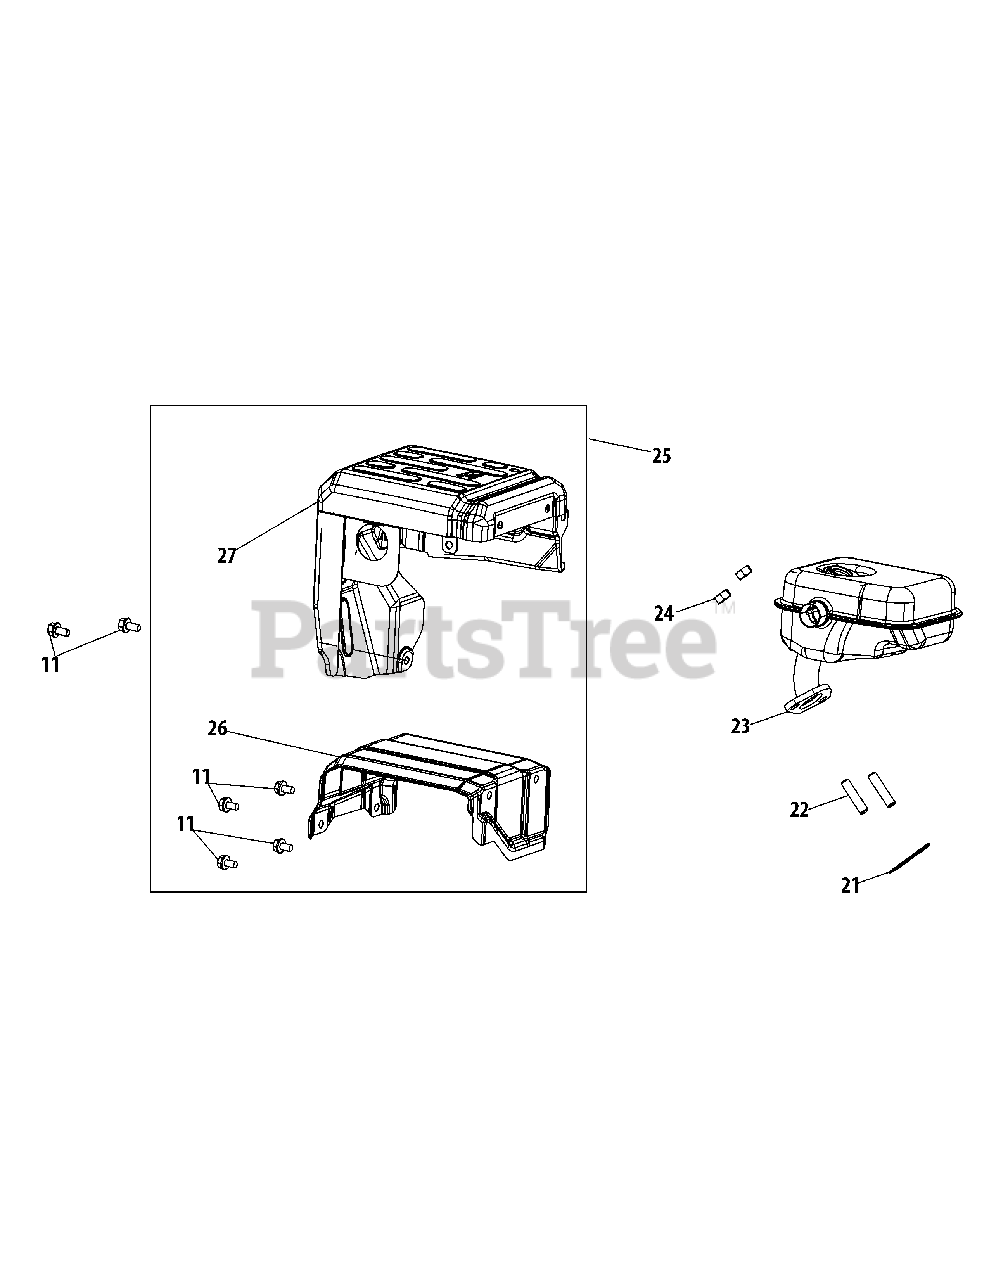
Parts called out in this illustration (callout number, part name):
11	Bolt, M6×12
21	Gasket, Muffler
22	Stud, M8×34
23	Muffler
24	Nut, M8
25	Muffler Guard
26	Muffler Inner Shield
27	Muffler Shield
